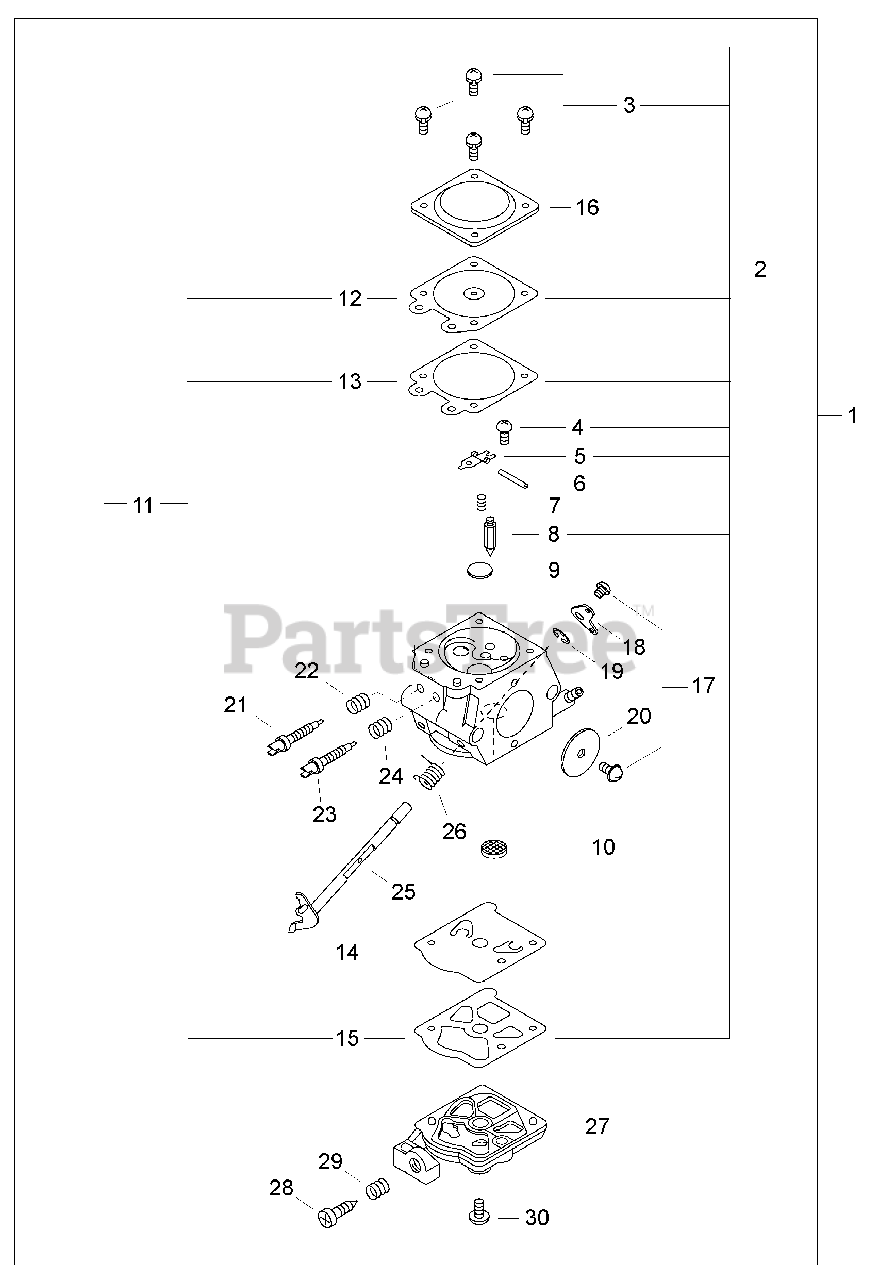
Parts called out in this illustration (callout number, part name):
1	CARBURETOR - WT-385A
2	REPAIR KIT, CARBURETOR
3	SCREW
4	SCREW, METERING LEVER PIN
5	LEVER, METERING
6	PIN, METERING LEVER
7	SPRING
8	VALVE, INLET NEEDLE
9	PLUG, WELCH
10	STRAINER
11	GASKET / DIAPHRAGM KIT
12	DIAPHRAGM, METERING
13	GASKET, METERING
14	DIAPHRAGM, PUMP
15	GASKET, FUEL PUMP
16	COVER, METERING DIAPHRAGM
18	LEVER, THROTTLE
20	VALVE, THROTTLE
21	NEEDLE, HIGH SPEED
22	SPRING, HIGH NEEDLE
23	NEEDLE, LOW SPEED
24	SPRING, NEEDLE
25	SHAFT, THROTTLE
26	SPRING, THROTTLE
27	COVER, FUEL PUMP
28	SCREW, IDLE ADJUST
29	SPRING, IDLE ADJUST
